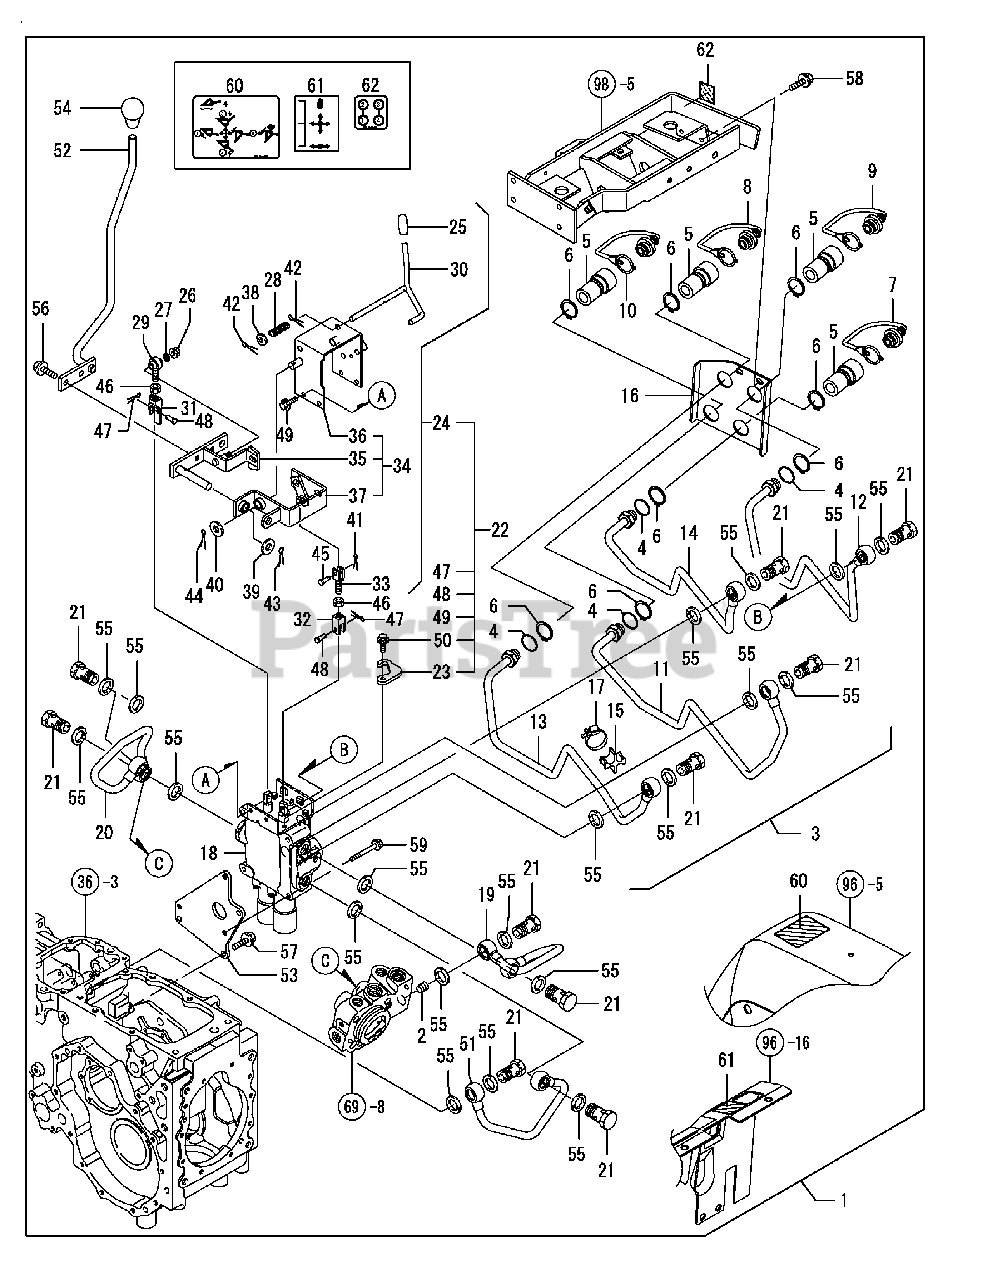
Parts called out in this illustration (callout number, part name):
3	SCV LINE ASSY
5	COUPLER, QUICK 3/8F
7	PLUG, DUST RED
8	PLUG, DUST BLUE
9	PLUG, DUST YELLOW
10	PLUG, DUST GREEN
11	HP PIPE (SCV-B1)
12	HP PIPE (SCV-B2)
13	HP PIPE (SCV-A1)
14	HP PIPE (SCV-A2)
16	SUPPORT, SCV COUPLER
19	LINE, SCV PUMP
20	LINE, SCV PBYD
23	PLATE, STOPPER
24	SCV LINK ASSY
25	KNOB
26	NUT W/WASHER 6
30	STOPPER, SCV LEVER
34	ARM ASSY, LINK
35	ARM, BUCKET CONTROL
36	SUPPORT, SCV LINK
37	ARM ASSY, SCV LINK
41	COTTER PIN 1.6X18
42	COTTER PIN 2.5X30
43	COTTER PIN 2.5X30
44	COTTER PIN 2.5X30
47	COTTER PIN 1.6X18
49	BOLT M 6X 16 PLATED
50	BOLT M 6X 16 PLATED
51	LINE, SCV DRAIN
56	BOLT M 8X 20 PLATED
57	BOLT M 8X 20 PLATED
58	BOLT M 8X 12 PLATED
59	BOLT M 8X 55 PLATED
60	LABEL, SCV LEVER
61	LABEL, SCV COUPLER
62	LABEL, SCV LOCK
